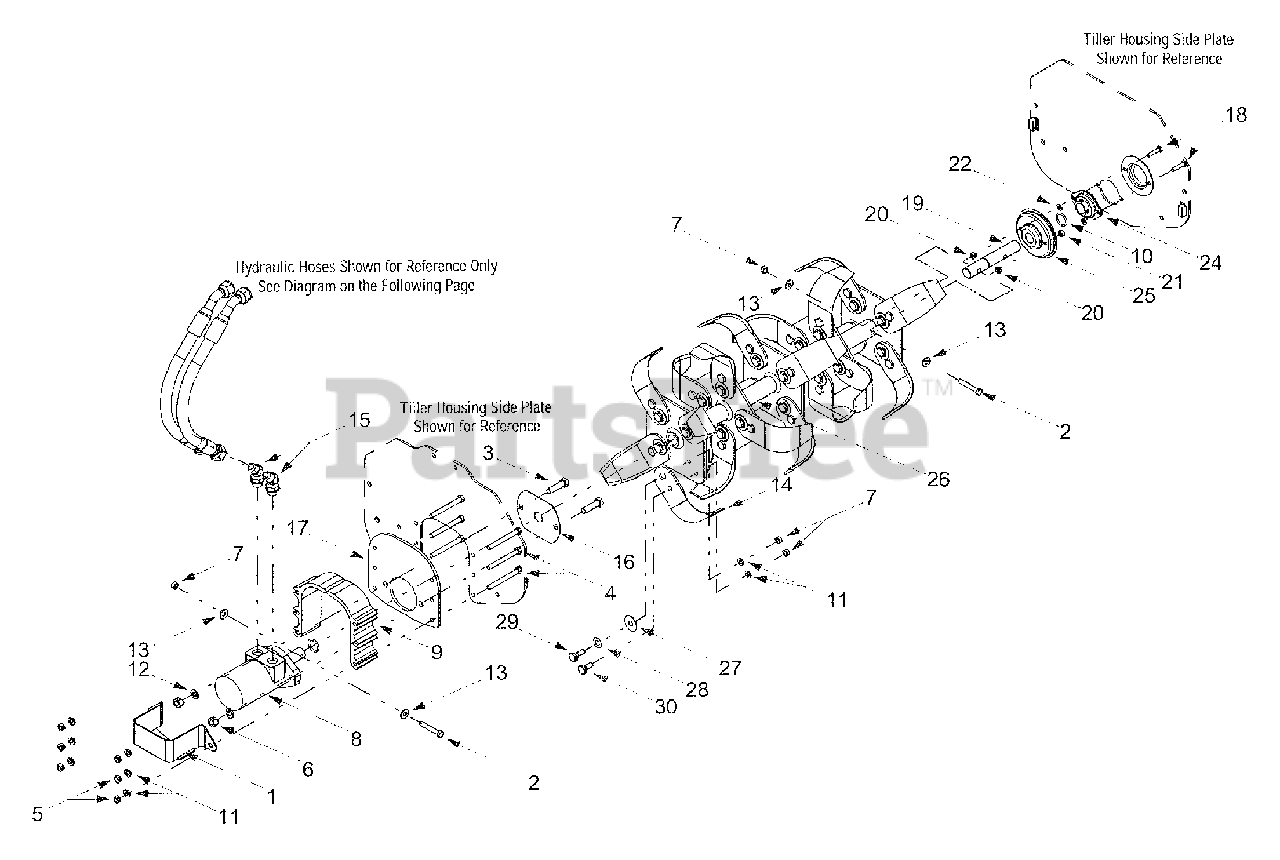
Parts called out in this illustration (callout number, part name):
1	Hydraulic Motor Guard
2	Hex Cap Screw, 3/8-24 x 2.25
3	Hex Cap Screw, 1/2-13 x 1.75
4	Hex Cap Screw, 3/8-16 x 3.5
5	Hex Lock Nut, 3/8-16
6	Hex Lock Nut, 1/2-13
7	Hex Lock Nut, 3/8-24
8	Eaton Hydraulic Motor
9	Hydraulic Motor Mounting Spacer
10	O Ring Seal
11	Lock Washer, 3/8
12	Lock Washer, 1/2
13	Flat Washer, .406 x .875 x .105
14	Articulating Tine
15	45° Hydraulic Adapter, 7/8
16	Hydraulic Motor Cover
17	Hydraulic Motor Mounting Plate
18	Hex Cap Screw, 5/16-18 x 1.25
19	Tine Shaft
20	Hex Lock Nut, 5/16-18
21	Hex Nut, 5/16-18
22	Lock Washer, 5/16
23	Flange Bearing, 1.0
24	Dust Cap Cover
25	Bearing Cover
26	Tine Adapter Assembly
27	Flat Washer, .51 x 1.5 x .07
28	Belleville Washer
29	Shoulder Screw, .49 x .21, 3/8-24
30	Shoulder Screw, .49 x .34, 3/8-24
